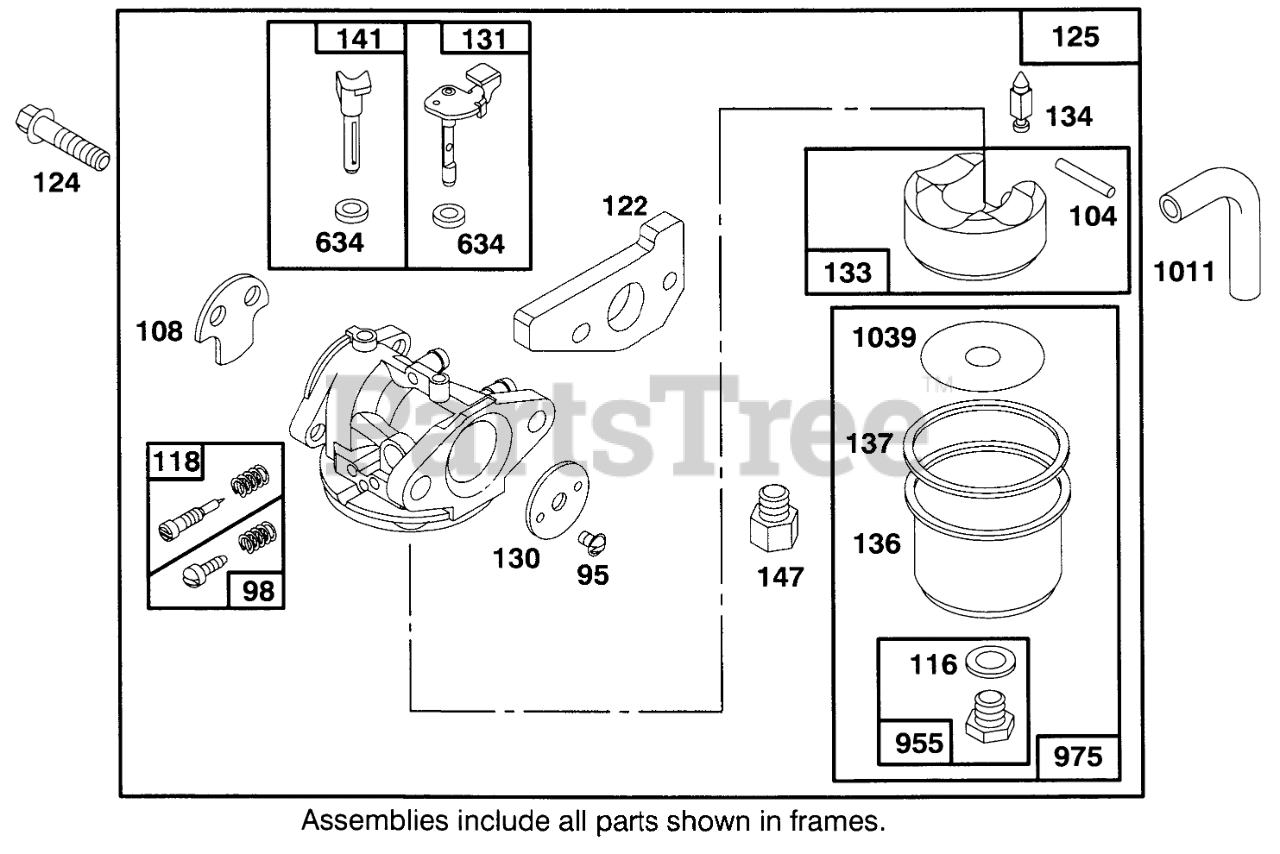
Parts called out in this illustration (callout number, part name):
95	SCREW - ROUND HEAD
98	IDLE ADJUSTING SCREW
104	FLOAT HINGE PIN
108	Valve-Choke
116	SEALING GASKET
118	VALVE KIT - NEEDLE
122	ADAPTER ASSEMBLY
124	HEX HEAD SCREW
125	CARBURETOR ASSEMBLY
130	THROTTLE VALVE
131	THROTTLE SHAFT
133	FLOAT-CARBURETOR
134	Valve-Inlet(Includes Seat)
136	FLOAT BOWL
137	FLOAT BOWL GASKET
141	CHOKE SHAFT
147	JET ADAPTER
634	SEAL WASHER
955	HEX HEAD SCREW
975	CARBURETOR BOWL ASM
1011	VENT TUBE
1039	FLOAT LIMITER
